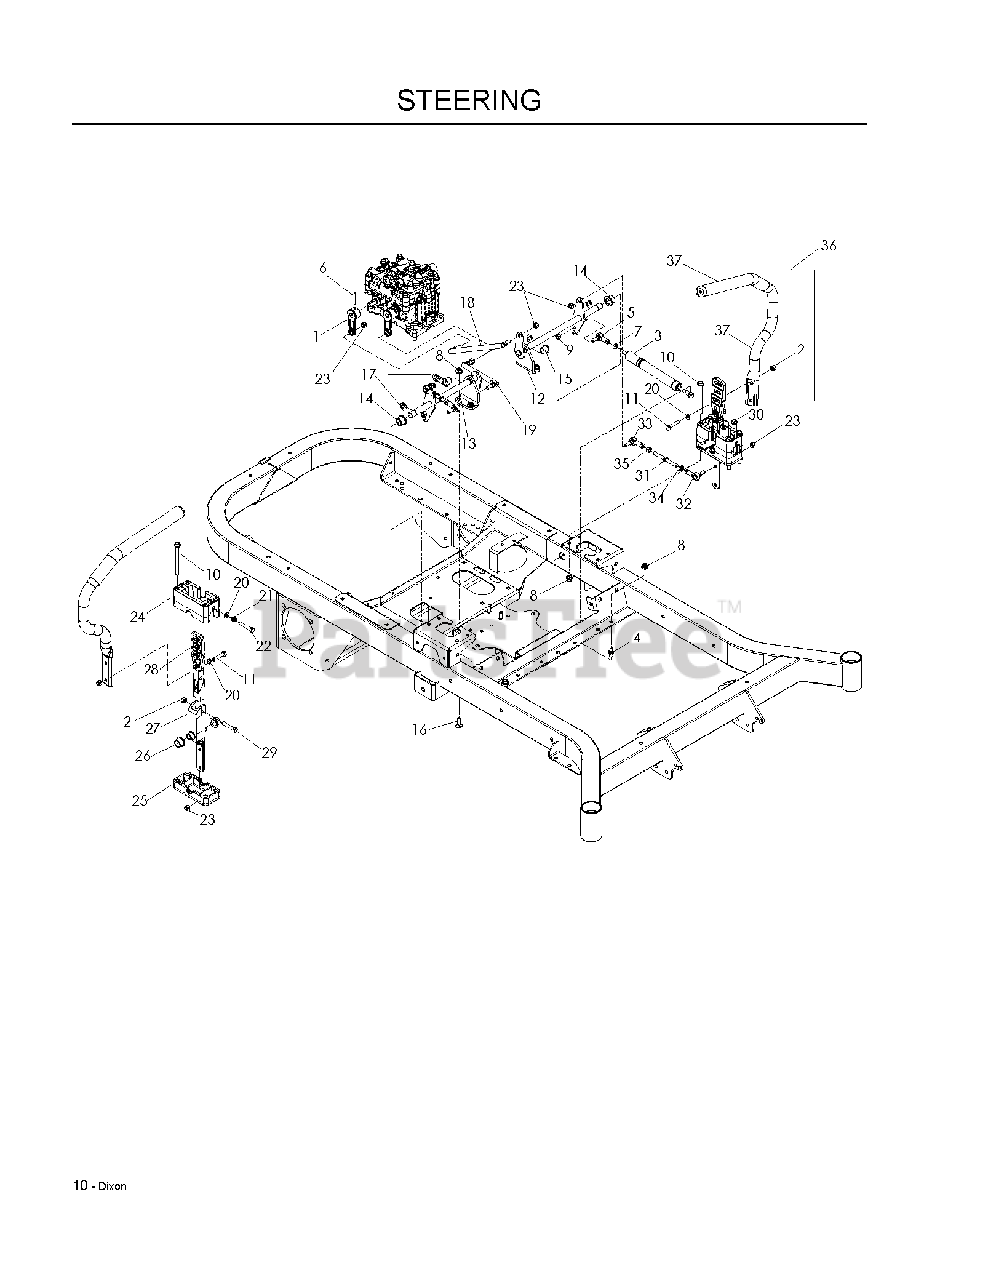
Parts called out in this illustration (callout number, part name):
1	ARM PUMP
2	NUT 5/16 NYLOC
3	DAMPENER W/SPRING
4	STUD.BALL.10MM
5	ROD END
6	PIN, SPIRAL, 5/32 X 1 1/2
7	NUT M8 X 1.25 STD HEX
8	5/16-18 NYLOC FLANGE NUT
9	NUT M8 NYLOC
10	HHFS 5/16-18 X 3 3/4
11	CAPSCREW 5/16 X 1/1/2 HEX HEAD
12	CONTROL WLDMT, LT
13	CONTROL WLDMT, RT
14	BUSHING, FLANGED, 5/8
15	BUSHING, CLIP, 5/8
16	RHSNB 5/16C X 1
17	E-RING 5/8
18	LINK, MOTION, LT
19	LINK, MOTION, RT
20	FLAT WASHER 5/16 SAE
22	HCS 5/16-18X1-3/4 TPBLT
23	NUT 5/16-24 CNTRLK
24	BLOCK, UPPER
25	BLOCK, LOWER
26	BEARING, FLANGE
27	PIVOT SECTION, DR CNTRL
28	MOUNT, DR CNTRL HANDLE
29	HCS 5/16C X 1 3/4
30	NUT 5/16C HEX
31	JACK SCREW
32	SPHERICAL ROD END, LH
33	SPHERICAL ROD END, RH
34	NUT 5/16F LEFTHAND
35	NUT 5/16F
36	LEVER.DRIVE.W/GRIP
37	GRIP - DRIVE LEVER
